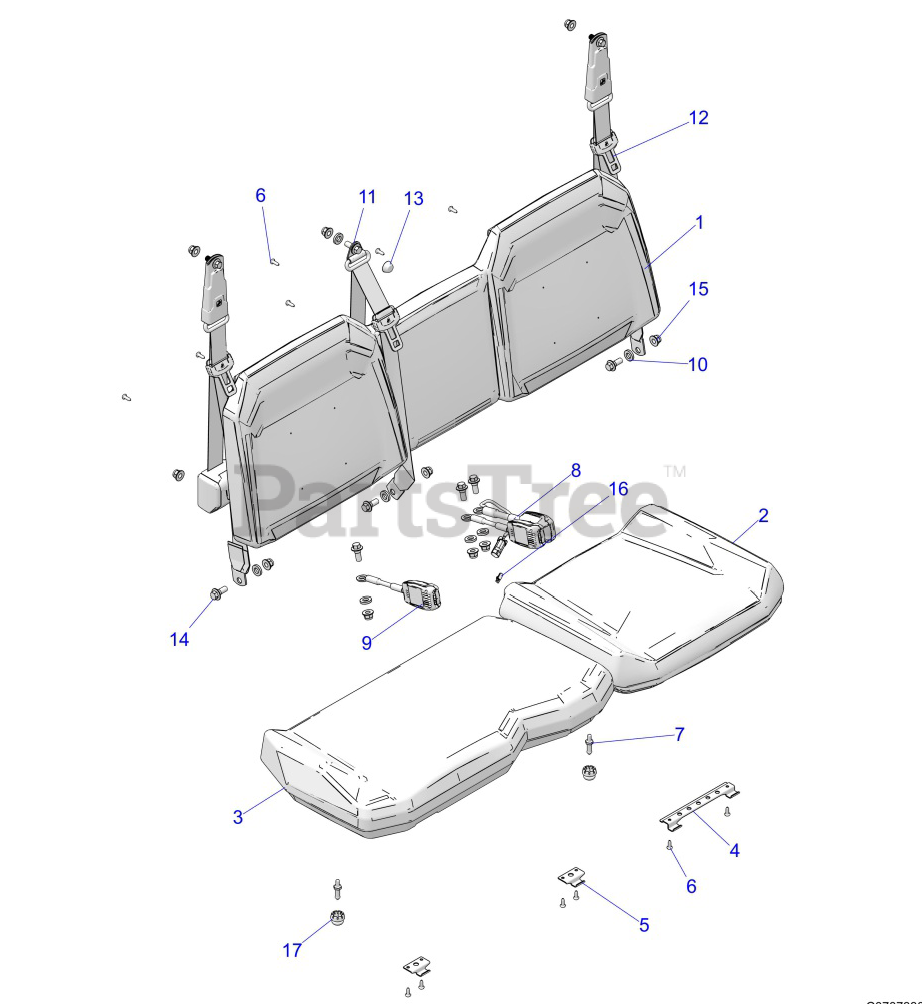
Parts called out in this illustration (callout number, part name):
1	ASM-SEAT,3PASS,BACK,GUNMETAL
4	BRKT-SEAT HINGE,DOUBLE
5	BRKT-SEAT HINGE
6	SCR-TX TRUSS-#14X3/4,HI/LO ZBK
7	PIN-SEAT LATCH
8	BUCKLE, SEATBELT, 90, SWITCH
9	BUCKLE-SEATBELT,9.6,PASSENGER
10	WASHER-SEATBELT,RUBBER
11	ASM-SEAT BELT,3PT,CENTER
12	ASM-SEAT BELT,3PT
13	CAP-BOLT HEAD
14	SCR-HXFLSH-M12X1.75-M14X9 ZOD
15	NUT-HXFL M12X1.75 NYLOC ZOD
16	CLIP-CONNECTOR,6.35MM HOLE
